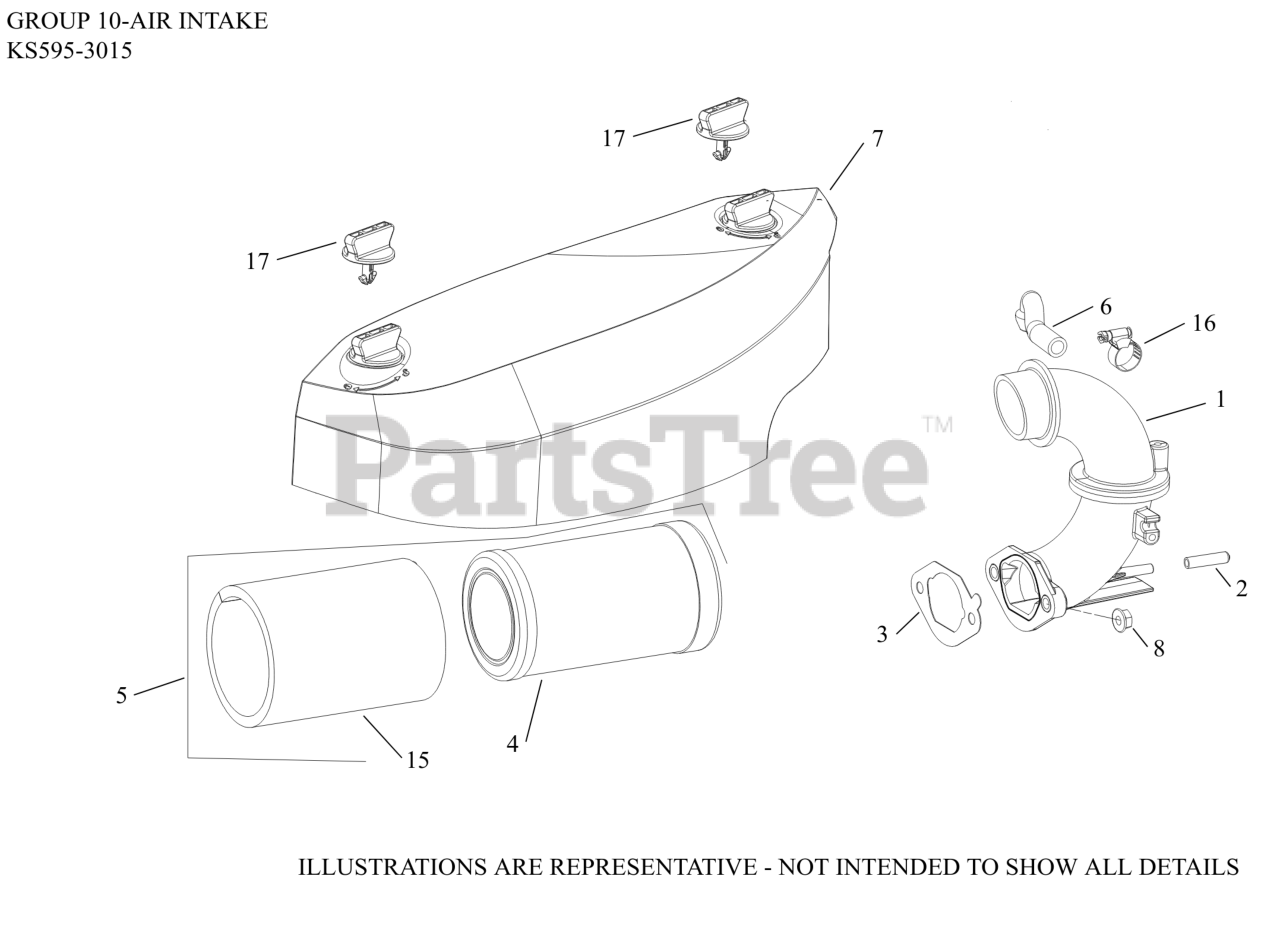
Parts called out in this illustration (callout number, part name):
1	ADAPTER, AIR CLEANER ASSY
2	CAP, MASKING
3	GASKET, CARBURETOR
4	ELEMENT, AIR FILTER
5	AIR FILTER KIT (STD)
6	HOSE, BREATHER
7	COVER, AIR CLEANER ASSY
8	NUT, FLG M6X1.0
15	ELEMENT, PRE-CLEANER
16	CLAMP, HOSE (KM)-USE 25 237 31-S
17	KNOB, AIR CLEANER COVER
